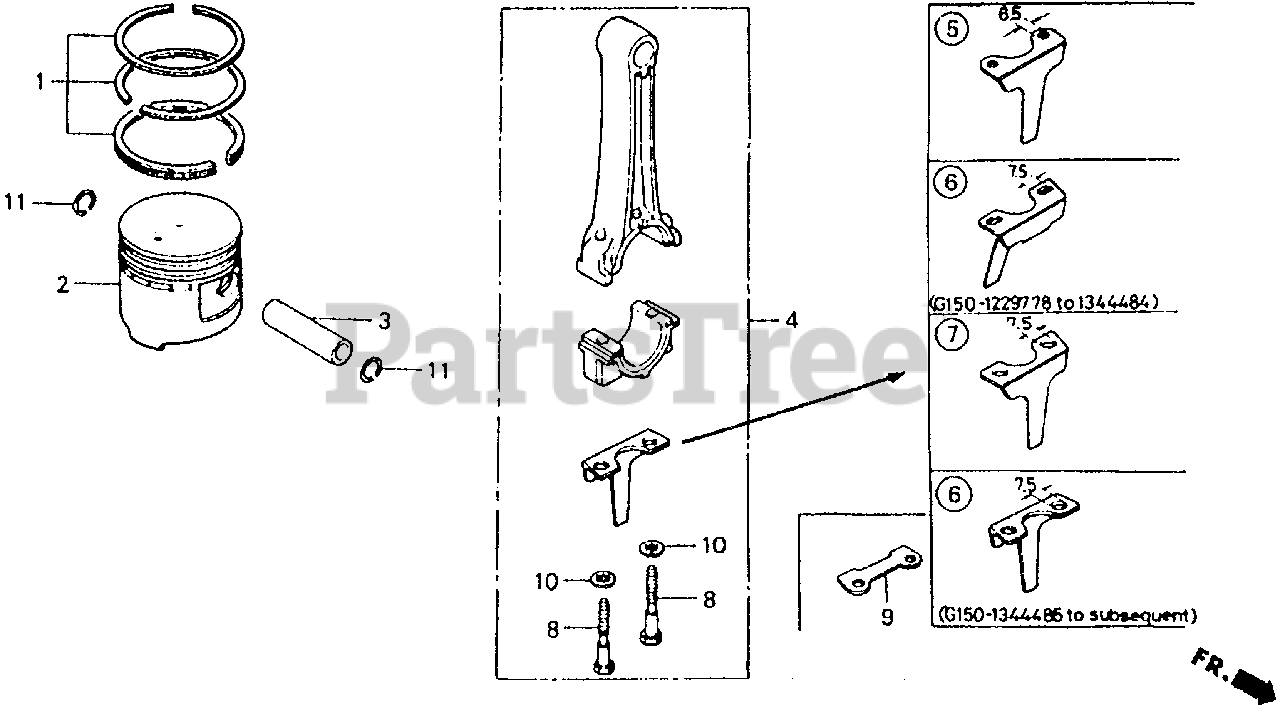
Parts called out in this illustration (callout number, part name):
1	RING SET, PISTON (STD)
1	RING SET, PISTON (OS 0.25) (OS)
1	RING SET, PISTON (OS 0.50) (OS)
1	RING SET, PISTON (0.75) (OS)
2	PISTON (STD)
2	PISTON (OS 0.25) (OS)
2	PISTON (OS 0.50) (OS)
2	PISTON (0.75) (OS)
3	PIN, PISTON
4	ROD ASSY., CONNECTING
4	ROD ASSY., CONNECTING (US 0.25)
6	DIPPER, CONNECTING ROD
8	BOLT, CONNECTING ROD (7MM)
10	WASHER, LOCK (7MM)
11	CLIP, PISTON PIN (15MM)
